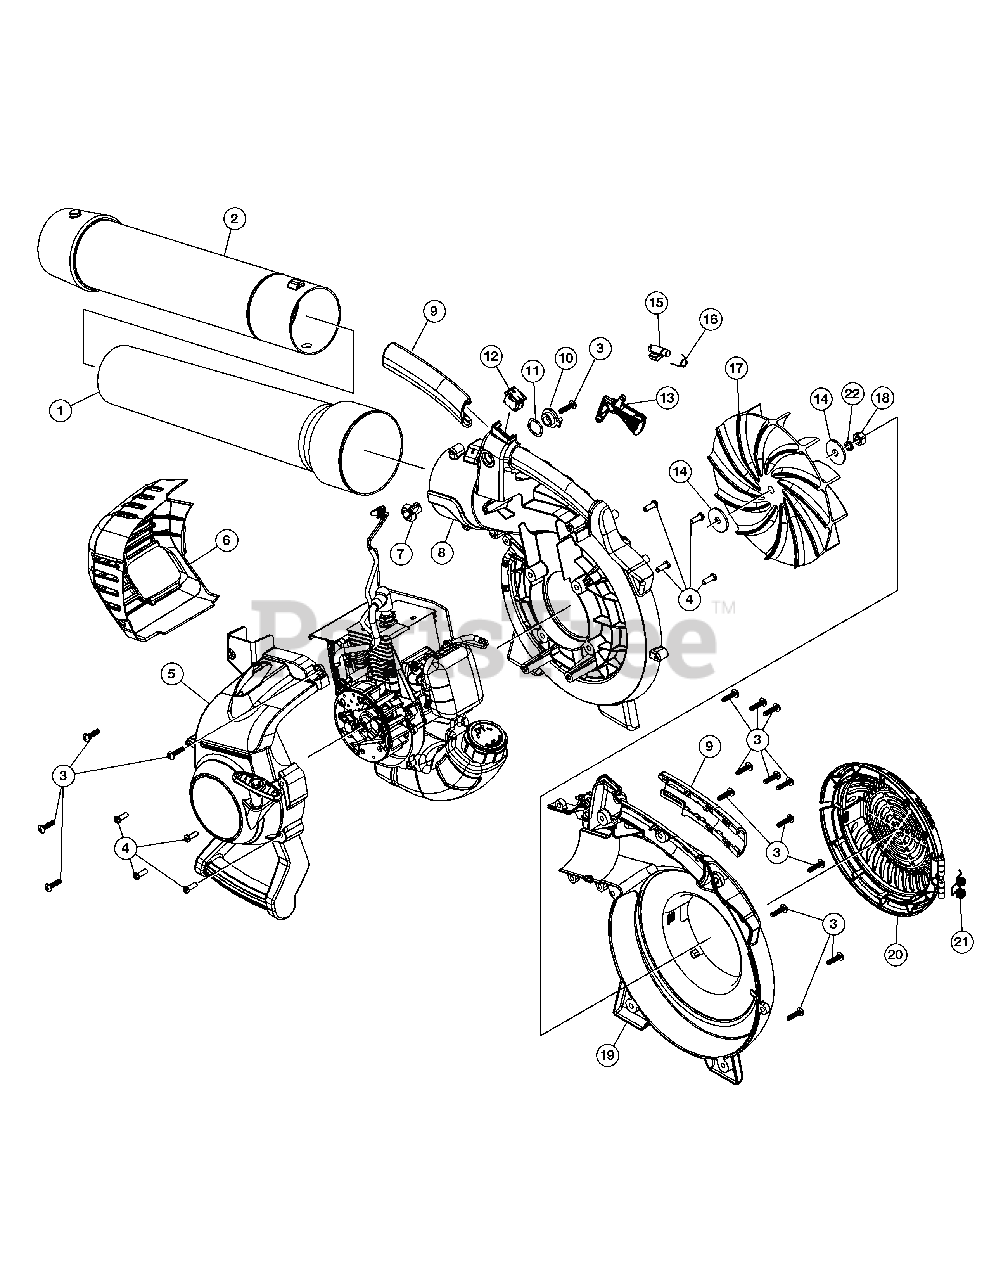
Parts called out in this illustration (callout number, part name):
1	Lower Tube
2	Upper Tube
4	Screw
5	Engine Cover Assembly (Incl. 3 & 4)
6	Muffler Cover Assembly (Incl. 3)
7	Outer Trigger Lock
8	Impeller Housing
9	Handle Grips
10	Inner Trigger Lock
11	Wavey Washer
13	Throttle Trigger
15	Latch Tube
16	Latch Spring
19	Impeller Housing
20	Intake Cover
22	Lock Washer
